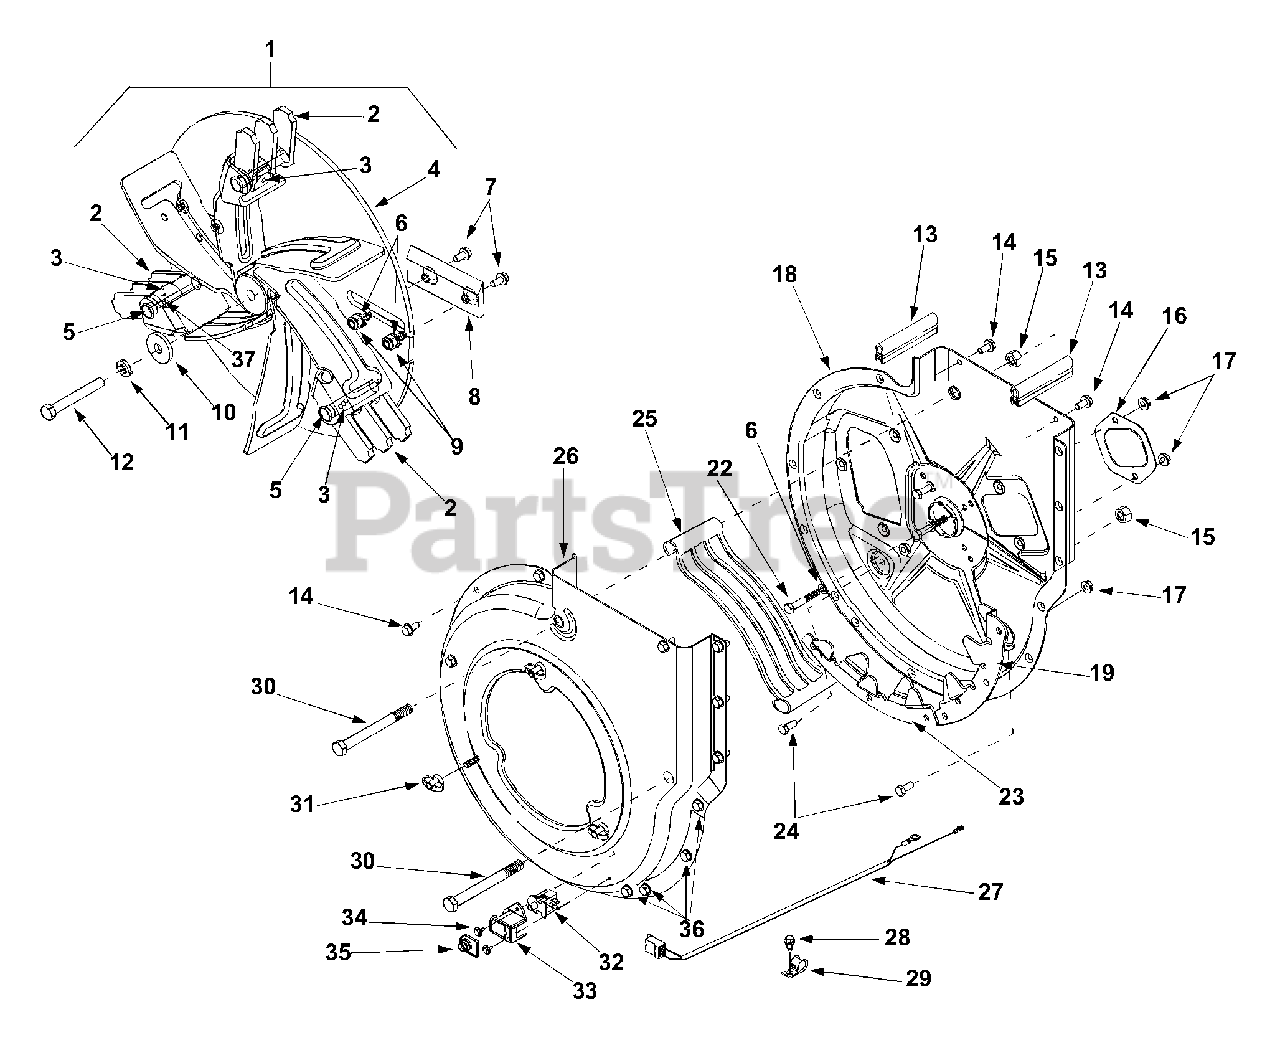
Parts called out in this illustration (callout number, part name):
1	Impeller Assembly: Complete
2	Flail Blade
3	Spiral Pin
4	Impeller Assembly
5	Clevis Pin
6	Lock Washer 5/16
7	Cap Screw 5/16-24 x 1.0
8	Chipper Blade
9	Hex Lock Nut 5/16-24
10	Flat Washer.406 x 1/1/4
11	Lock Washer 3/8
12	Hex Cap Screw 3/8-24 x 2.75
13	Rubber Seal
14	Hex Washer Screw 5/16-18
15	Hex Lock Nut 1/2-13
17	Hex Flange Lock Nut 5/16-18
22	Hex Cap Screw 5/16-18 x 2
24	Hex Cap Screw 5/16-18 x.75
25	Discharge Screen
27	Wire Harness
28	TT Screw 1/4-14 x 0.625"
30	Hex Cap Screw 1/2-13 x 5.0
31	Knob 5/16-18
32	Switch
33	Safety Switch Mounting Cover
34	Hex Washer Screw
35	Switch Cover
36	LD Screw 5/16-18 x 0.75"
37	Retaining Pin Clip
